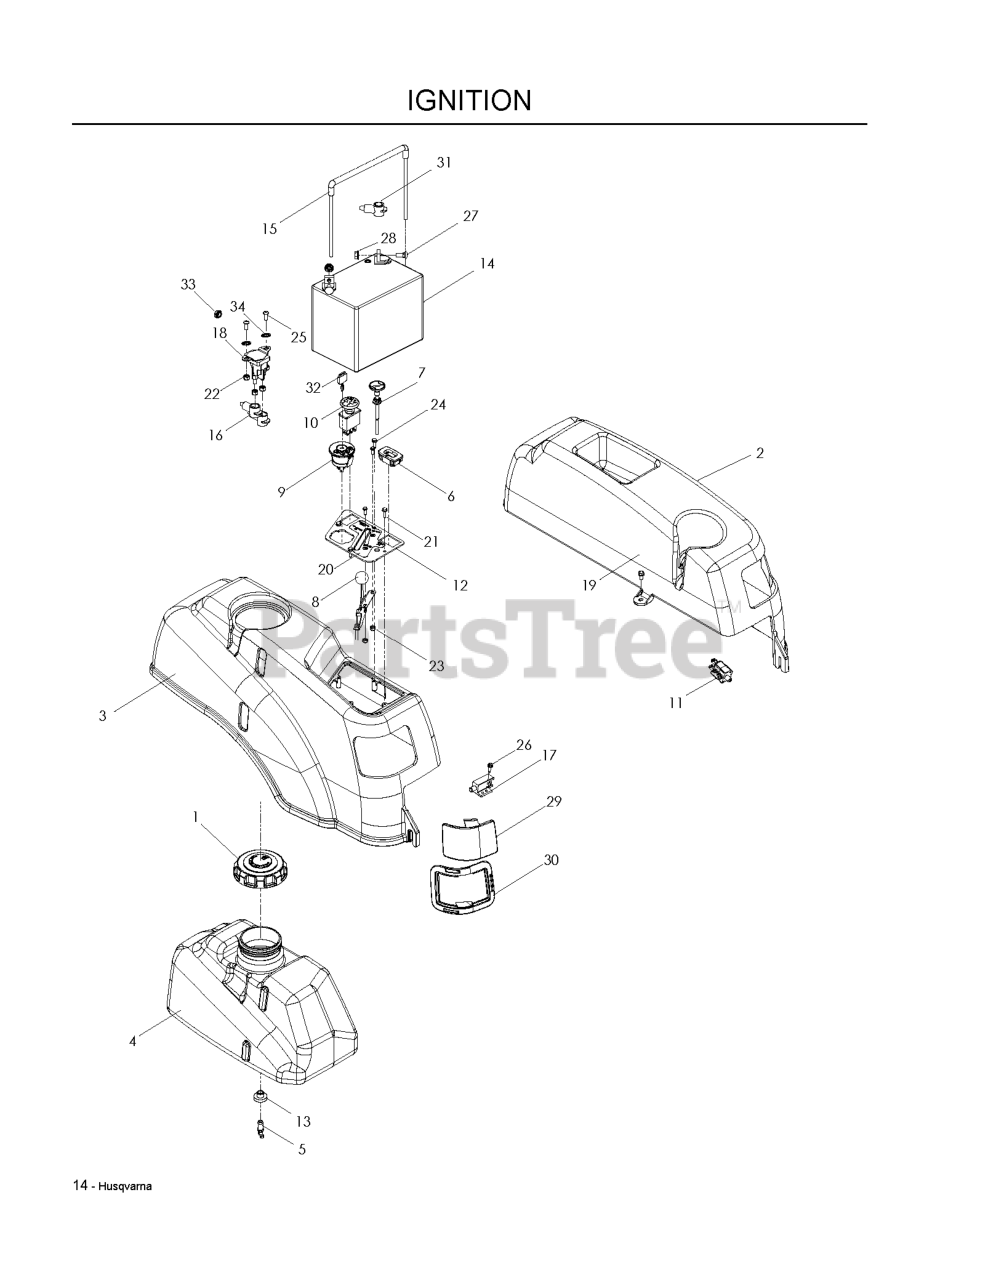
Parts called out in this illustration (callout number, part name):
1	FUEL CAP, HTC
2	FENDER, LT
3	RP.FENDER, RT
5	STEM, FUEL TANK
6	HOUR METER
7	CHOKE CONTROL
8	THROTTLE CABLE
9	RP IGNITION SWITCH
10	RP.SWITCH, BLADE
11	SWITCH, BRAKE 3P
12	CONSOLE.PLATE.BLACK
13	RUBBER GROMMET
14	BATTERY, 12 V 330 AMP
15	BATTERY TIE DOWN ASSEMBLY
16	TERMINAL COVER-SM
17	SWITCH, INTERLOCK
19	BOLT 1/4-20 X 1/2 HWST
20	DECAL, IGNITION CONSOLE
21	HCS #10-24 X 1/2
22	NUT.1/4-20.HEX.NYLOC.ZD
23	NUT 10-24 NYLOC
24	SCR #10-12X3/4 HEX WAS HD ZD
25	SCR 1/4-20 X 5/8 BTN SKT HD ZD
26	SCREW #10 X 1/2 SELF TAPPING
27	BOLT 5/16C X 3/4" CARRIAGE
28	NUT 5/16C WHIZ
29	LENS, COLORED LEFT
29	LENS, COLORED RIGHT
30	RT HEADLIGHT RIM GREY
30	LEFT HEADLIGHT RIM GREY
32	KEY
33	JAM NUT 1/4C (2 2 PW01)
34	WASHER 1/4 INT TOOTH
